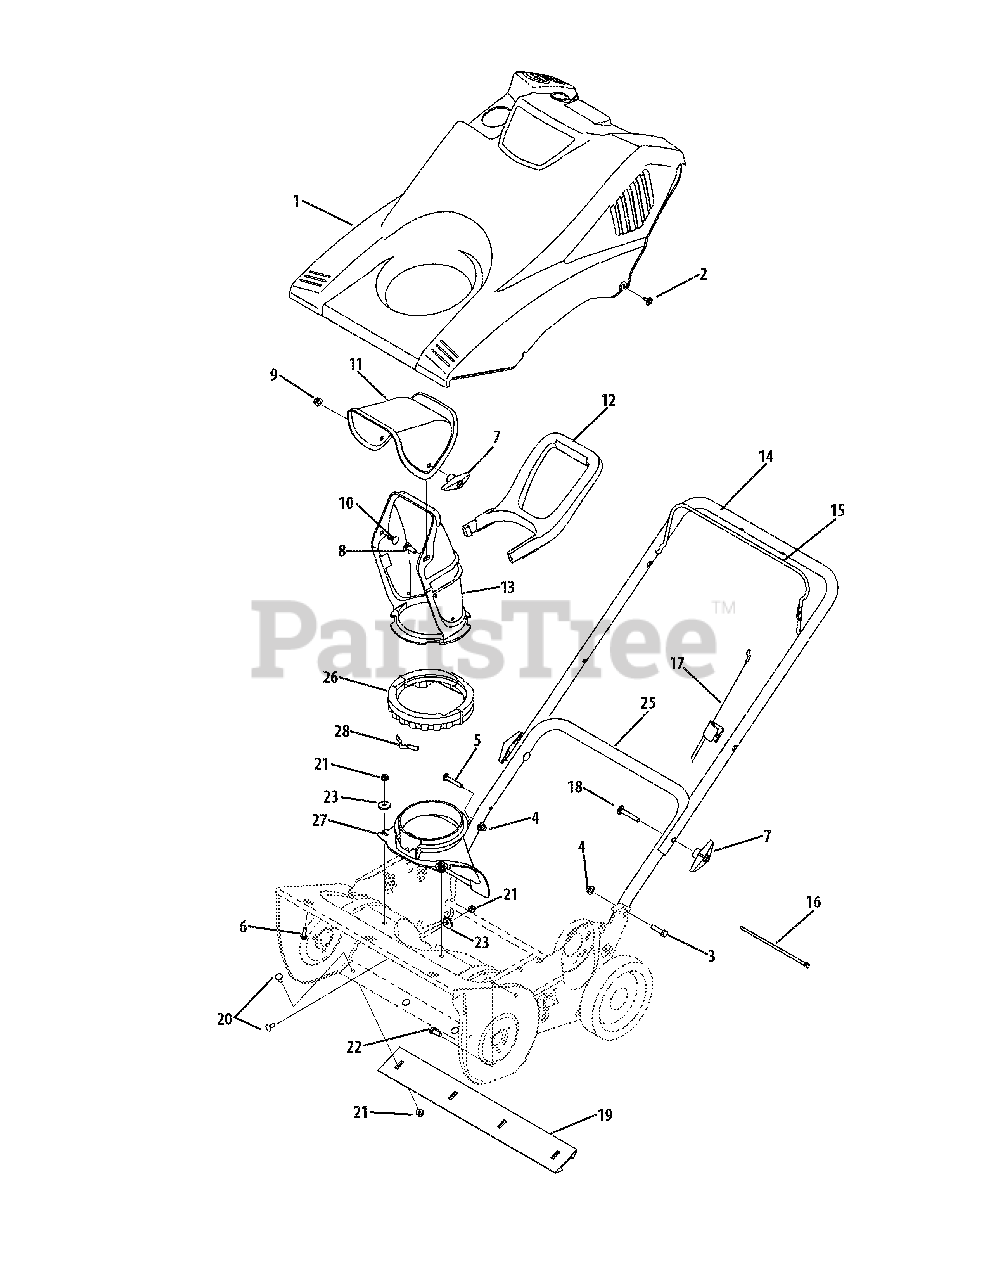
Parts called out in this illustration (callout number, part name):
1	Shroud
2	Hex Wash B-Tapp Scr #10-16 x .62" Lg.
3	Hex Scr. .312-18 x 1.250
4	Flange Locknut 5/16-18 Gr. F, Nylon
5	Hex Scr. 5/16-18 x 1.50 Gr. 5
6	Hex Tapp Scr 1/4 x .75" Lg.
7	Handle Knob Assembly
8	Carriage Screw 5/16-18 x 1.0
9	Flange Locknut 5/16-18 Gr. F, Nylon
10	Carriage Bolt 5/16-18 x .75
11	Upper Chute
12	Chute Handle
13	Lower Chute 5" Dia
14	Upper Handle
15	Bail Control
16	Cable Tie
17	Control Cable
18	Carriage Bolt 5/16-18 x 2.0
19	Shave Plate
20	Carriage Bolt 1/4-20 x .62
21	Hex L-Flanged Nut 1/4-20 Gr. F Nylon
22	Hex Bolt 5/16-18 x .75" Lg. Gr. 5
23	Flat Washer .25 ID x .93 OD x .125
26	Ring-Lower Chute
27	Chute Adapter 5" Dia
28	Chute Adjustment Spring
